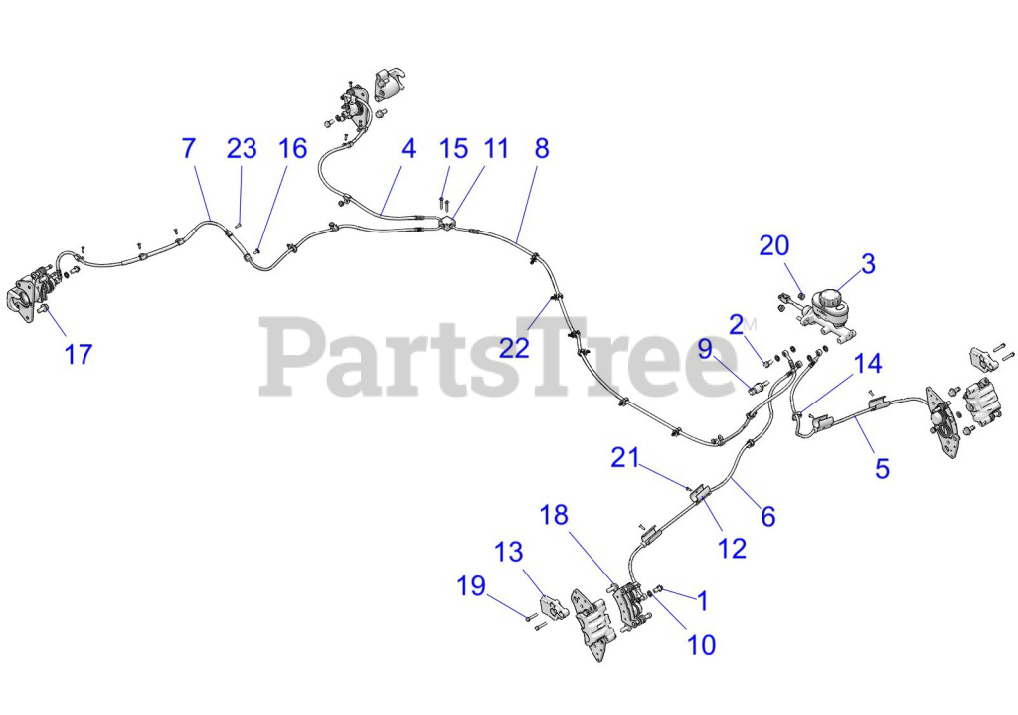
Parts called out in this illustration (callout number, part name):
1	BOLT-BANJO-10MMX1.00
2	BOLT-BANJO- 10MM X 1.25-6G
3	ASM-M/C-T-FLANGE-3/4 BORE
4	LINE-BRK-RL-41.1-45F-90SB-290J
7	LINE-BRK,RR,J
8	LINE-BRK-M/T-105.4-20B-30F-263
9	SWITCH-BRK, M10X1.25, DBL, SEALED
9	SWITCH-BRK-M10X1.25-DBL-SEALED
10	SEAL-STAT-O-3/8-70EP
11	FITTING-TEE-BRAKE
12	RETAINER-BRAKE LINE-1"
13	SCRAPER-BRAKE- FRONT
14	CLIP-ROUTING
16	SCREW(10)
17	BOLT-M10X1.25X20-HXFLG-OLV D
18	BOLT-M10X1.25X25-HXFLG-W/PATCH
19	SCR-HXFL-M6X1.0X35-W/PATCHLOK
20	NUT-M8X1.25-FLG-NYLOC-OLIVE D
21	POP RIVET(50)
22	CLIP-NYLON-C-FIR-TREE
